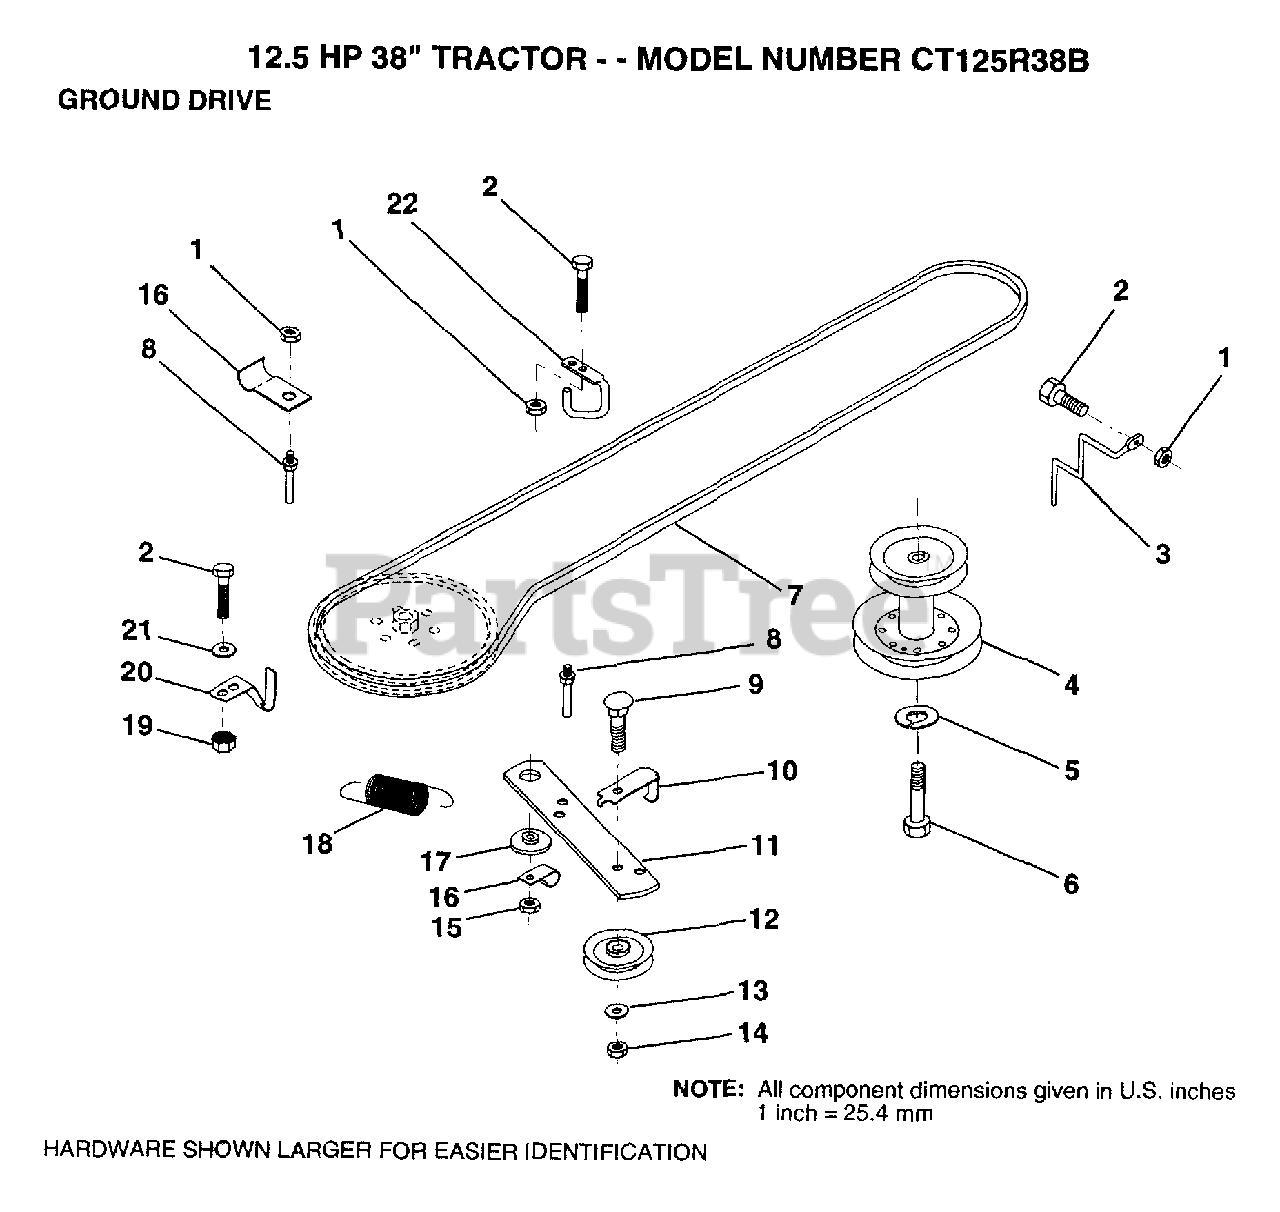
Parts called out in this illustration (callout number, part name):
2	BOLT
3	KEEPER MWR DR BLT
5	LOCKWASHER
6	BOLT
7	BELT
8	"KEEPER,DRIVE BELT"
9	BOLT
10	"KEEP,IDLER DR BEL"
13	WASHER
14	LOCKNUT
16	"CLIP,INSULATOR"
17	SPACER RETAINER
20	"KEEPER,DR BELT "
21	WASHER
22	"KEEPER,FRA DR BEL"
